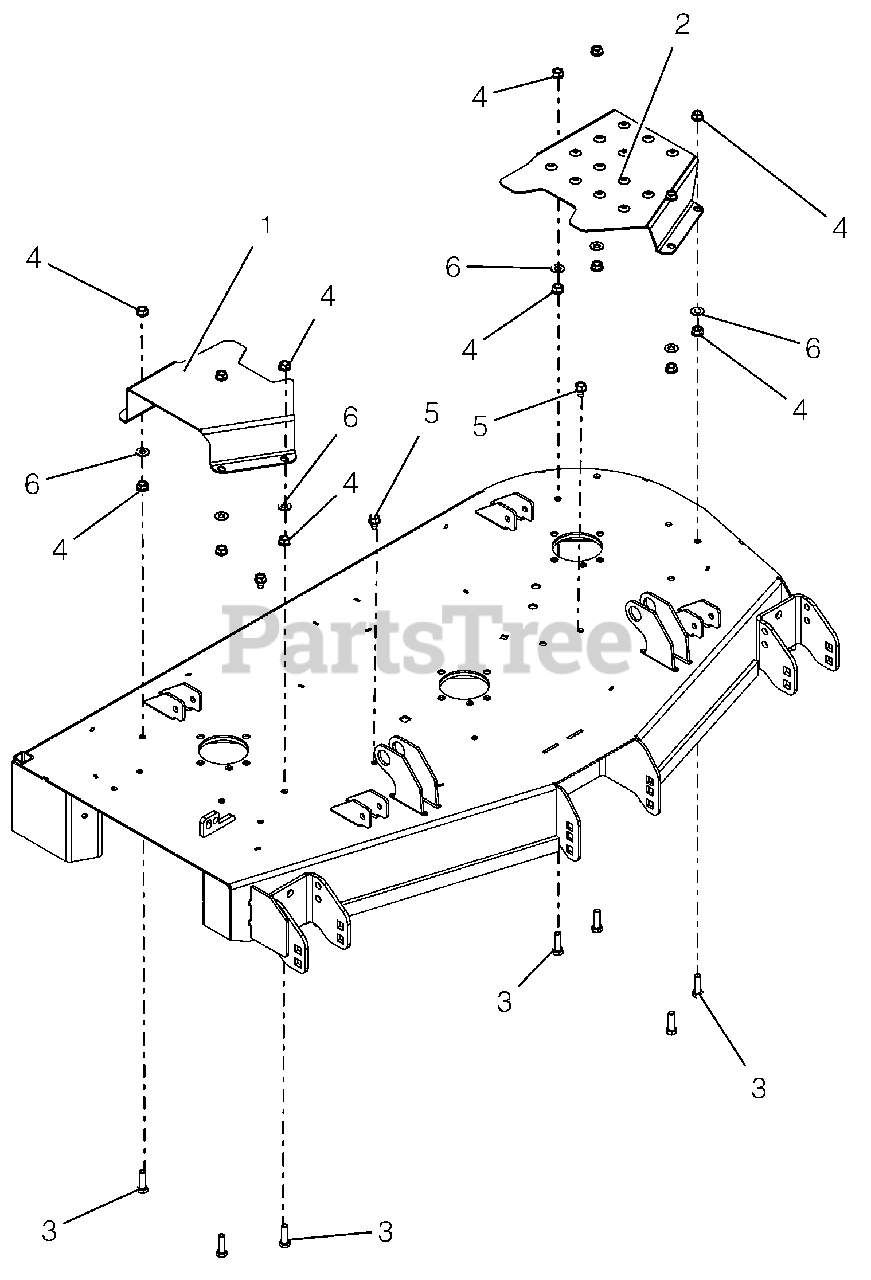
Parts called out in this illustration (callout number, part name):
1	COVER, BELT 48" RIGHT
2	COVER, BELT 48" LEFT
3	@BLT-HEX .38-16X1.25 GR5 YWZC
4	@NUT-SPNLK-FLG .375-16 YWZC
5	@SCR-TAP .38-16X.50 HWH TR YWZ
6	@WSHR-FL-STL.406X.812X.065 YWZ
